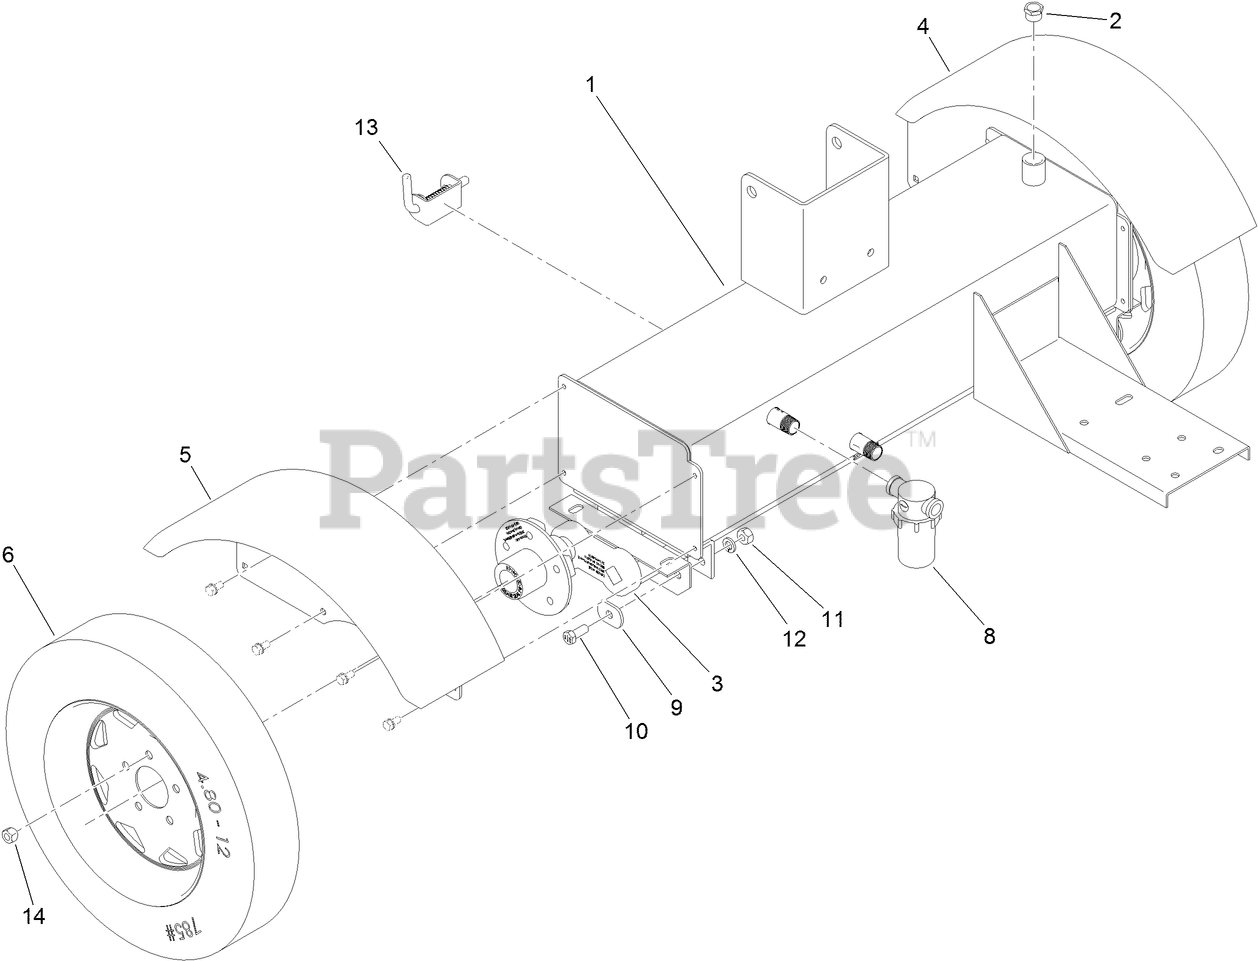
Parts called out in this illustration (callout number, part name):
1	RESERVOIR ASM
2	CAP-BREATHER
3	AXLE-TORFLEX
4	FENDER-LH
5	FENDER-RH
6	TIRE
8	FILTER-HYD
9	WASHER-HARDENED
10	Capscrew
11	NUT-HHF, WHIZ
12	WASHER-LOCK
13	PIN-LATCHING
14	NUT-LUG
